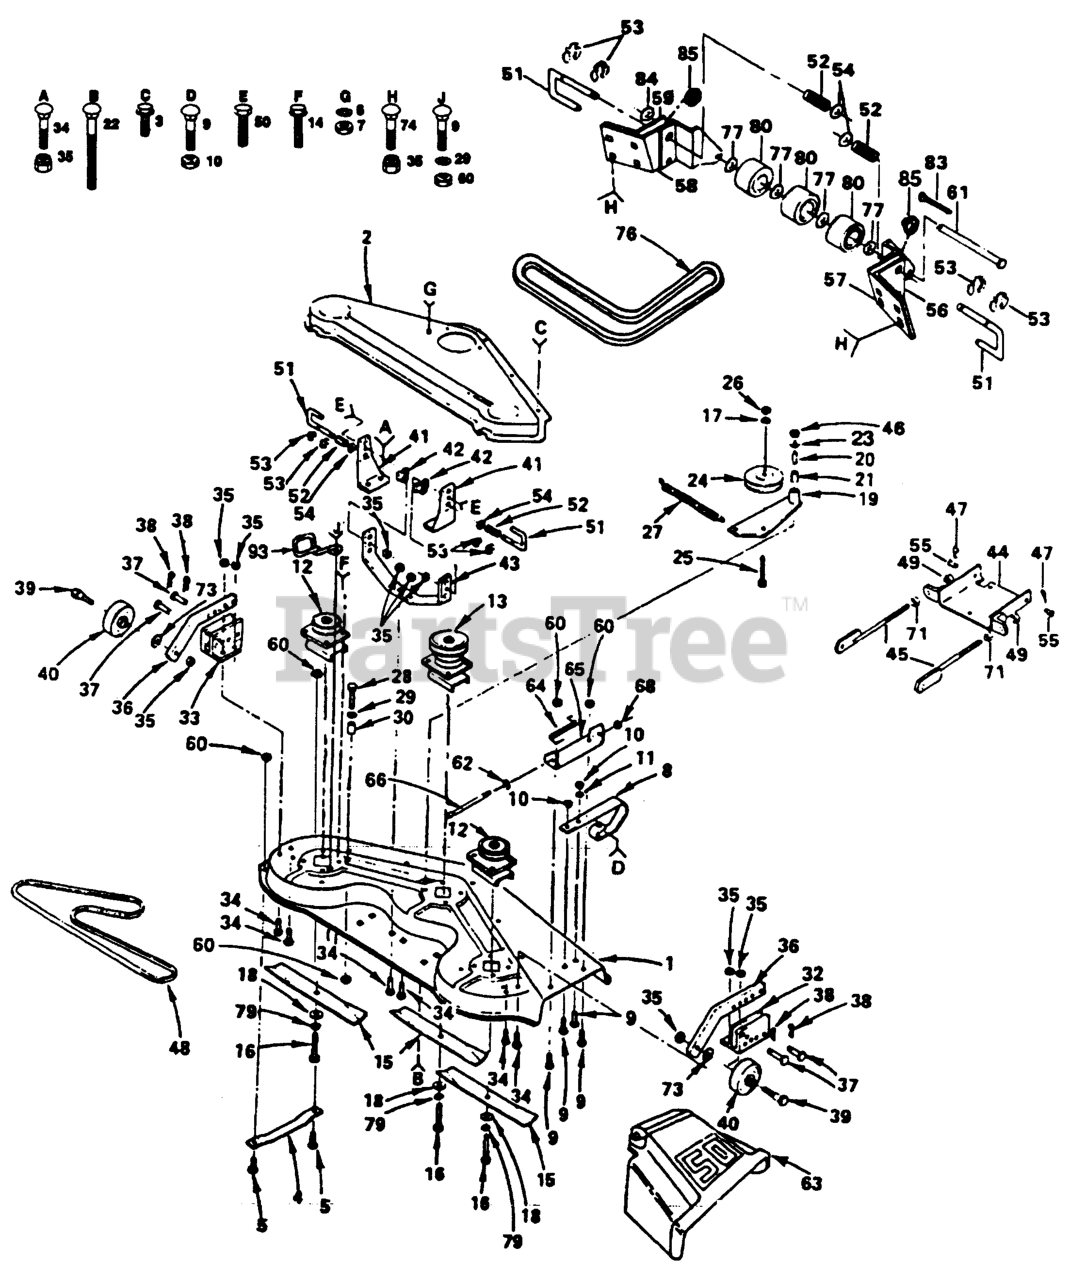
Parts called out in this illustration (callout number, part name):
1	HOUSING
2	CVR DRIVE DECK
3	Screw, Hex Washer Thr. Roll 5/16-18 x 1/2
4	RUNNER-LH M
5	BOLT.CARR.5/16-18X5/8.SHORT
6	WASHER.LOCK.HVY.HLCL.SPR.5/16
7	NUT
8	RUNNER T
9	RP BOLT 5/16-18 X3/4 ZN/YEL GR
11	WASHER
12	MANDRELL
13	MANDREL, PRIMARY
14	SCREW
15	BLADE.50".STANDARD.LIFT
16	BOLT.3/8-24X1-1/2
17	WASHER, LOCK 3/8
18	WASHER
19	ARM ASSY GT
20	BEARING ASSY M
21	BEARING ASSY M
22	Bolt, Carriage 5/16 - 18 x 2-3/4
23	Washer 11132 x 1-1/8 x 16 Gauge
24	IDLER-FLAT T
25	BOLT
26	NUT.HEX.3/8-16UNC
28	BOLT.5/16-18X1-1/4 FULL.THREAD
29	WASHER M
30	SPACER SPLIT LT
32	GUAGE WHL BRKT GT
33	GAUGE WHL BRKT GT
34	Bolt, Carriage 3/8-16 x 3/4
36	GUAGE WHL BAR GT
37	CLEVIS PIN T
38	RETAINER-SPRNG RB
39	BOLT M
40	WHEEL.GAUGE.BLK.4.93
41	SUSP BRKT GT
43	SUSP BRACE GT
45	BRACKET NLA
46	JAM NUT TI
47	SPRING RETAINER
49	NUT LTV
50	Bolt, Hex 3/8-16 x 1-3/8
51	RELEASE PIN GT
52	SPRING.COMPRESSION
54	WASHER GT
55	CLEVIS PIN GT
60	LOCKNUT
61	PIVOT PIN T
62	Washer 11/32 x 5/8 x 16 Gauge
63	SHIELD.DEFLECTOR.MOWER.50"BLK.
64	DEFLECTOR SPRG T
65	BRACKET, DEFLECTOR
66	ROD-HINGE T
68	NUT PUSH M
71	NUT.HEX.3/8-16UNC
73	Washer 17/32 x 15/16 x 12 Gauge
76	BELT-V.93.5.MOWER
77	WASHER T
79	LOCKWASHER
83	COTTER PIN
84	WASHER
93	BELT RETIANER
